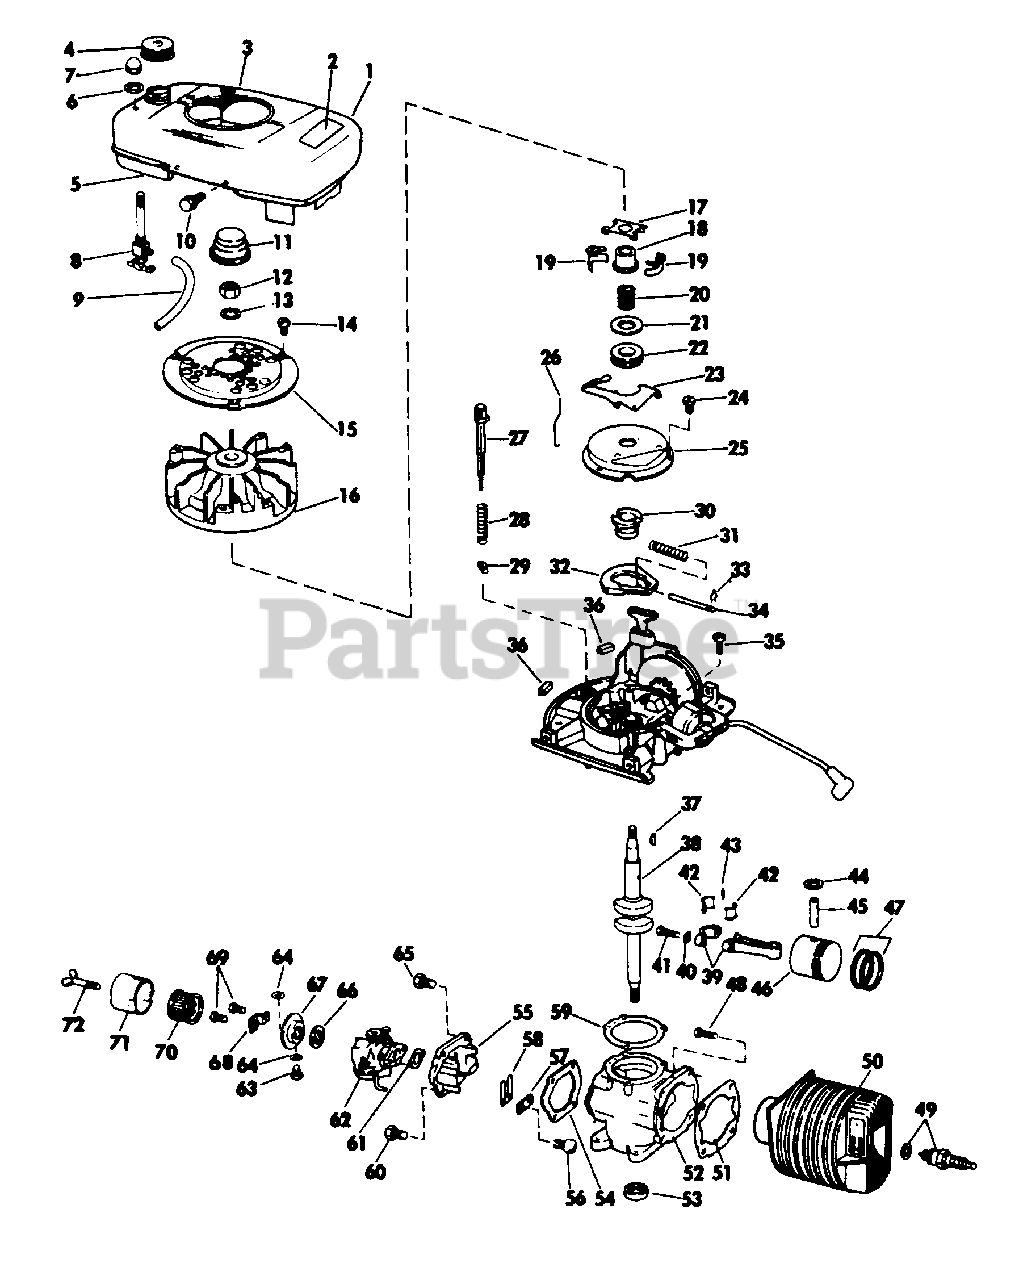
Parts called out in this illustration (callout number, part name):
1	Decal-"LAWN-BOY"
2	Decal-Instruction
3	Shroud & Shield Assembly
4	Cap & Gasket Assembly
5	Gas Tank Assembly
6	Lockwasher
7	Acorn Nut
8	Shut-Off Valve
9	Gas Line
10	Screw-Shroud to Arm. Plate
11	Cap-Flywheel Screen
12	Nut-Flywheel
13	Lockwasher-Flywheel
14	Screw-Thd. Cutting
15	Screen-Flywheel
16	Flywheel Assembly
17	Yoke-Governor
18	Collar-Governor
19	Weight-Governor
20	Spring-Governor
21	Thrust Washer
22	Collar-Thrust
23	Lever-Governor
24	Screw-Attaching Dust Cover
25	Dust Cover
26	Rod-Governor
27	Bar-Shut-Off & Primer
28	Spring-Shut-Off Switch
29	Blade-Switch
30	Cam-Spark Advance
31	Spring-Spark Advance
32	Flyweight-Spark Advance
33	Retainer-Spring
34	Pin-Spark Advance
35	Screw-Arm. Plate to Crankcase
36	Pad-Rubber, Armature Plate
37	Key-Crankshaft
38	Crankshaft
39	Connecting Rod Assembly
40	Lockplate-Conn. Rod Scr.
41	Scr.-Connecting Rod
42	Liners-Connecting Rod
43	Needle Bearing Set
44	Retaining Ring
45	Wrist Pin
47	Ring Assembly-Piston
48	Screw-Mch., Cylinder to C'case
49	Spark Plug & Gasket
50	Cylinder & Sleeve Assembly
51	Gasket-Cylinder to Crankcase
52	Crankcase & Seal Assembly
53	Oil Seal
54	Gasket-Reed Plate
55	Reed Plate Assembly
56	Screw-Machine
57	Plate-Back-Up
59	Gasket-C'case to Arm. Pl. .005 in.
59	Gasket-C'case to Arm. Pl. .010 in.
60	Scr.-Hex Hd., Reed Pl. to C'case
61	Gasket-Carburetor
62	Carburetor Assembly
63	Fastener, Felt
64	Felt-Filter Drain
65	Scr.-Hex Hd., Reed Pl. to C'case
67	Cup-Air Filter
68	Bracket Air Filter
69	Screw-Air Filter
70	Cartridge-Air Filter
71	Cover-Air Filter
72	Screw-Thumb
